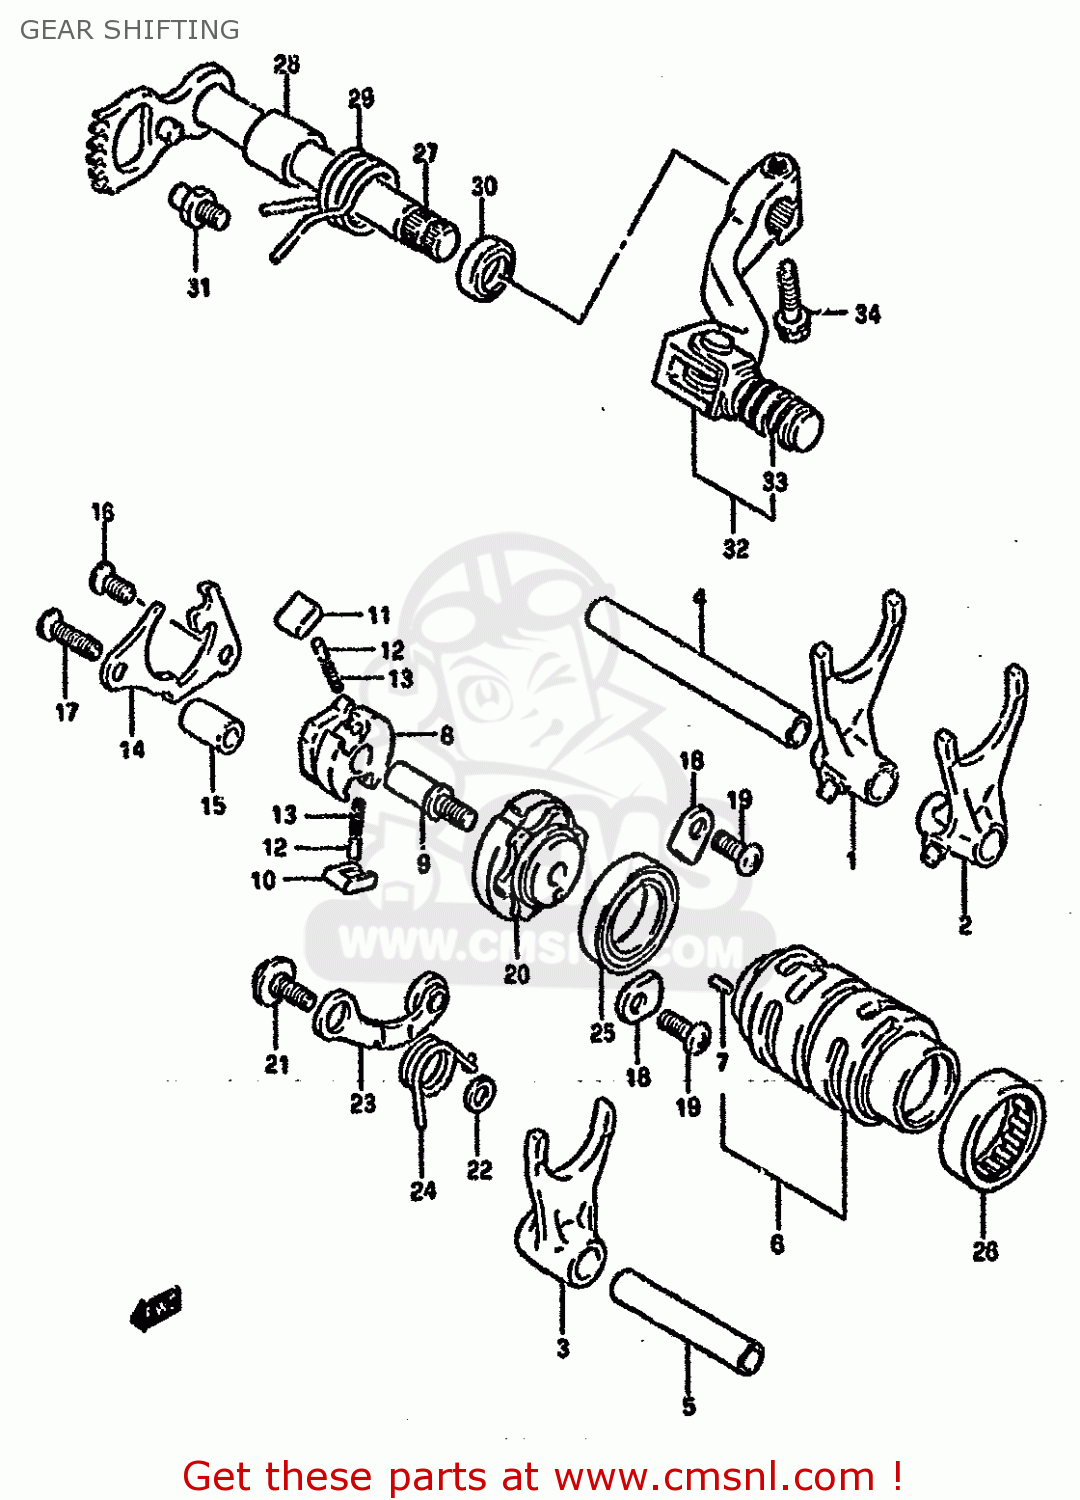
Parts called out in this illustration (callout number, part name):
1	FORK,GEAR SHIFT NO.1
2	FORK,GEAR SHIFT NO.2
3	FORK,GEAR SHIFT NO.3
4	SHAFT,GEAR SHIFT FORK
5	SHAFT,GEAR SHIFT FORK
6	CAM,GEAR SHIFT
7	PIN
8	GEAR,GEARSHIFT CAM DRIVE
9	PIN,SHIFT CAM DRIVEN GEAR
10	PAWL,GEAR SHIFT NO.1
11	PAWL,GEAR SHIFT NO.2
12	PIN(5X8)
13	SPRING
14	LIFTER,GEAR SHIFT POLE
15	SPACER(6.2X12X18)
16	SCREW
17	SCREW
18	RETAINER
19	SCREW
20	PLATE,SHIFT CAM STOPPER
21	BOLT(6X14.3)
22	WASHER
23	STOPPER,SHIFT CAM
24	SPRING
25	BEARING
26	BEARING(30X37X12)
27	SHAFT,GEAR SHIFT
28	SPACER(14X20X17.5)
29	SPRING
30	SEAL,OIL(14X22X6)
31	STOPPER,GEAR SHIFT CAM
32	LEVER ASSEMBLY,GEAR SHIFTING
33	RUBBER,GEAR SHIFT PEDAL
34	BOLT
